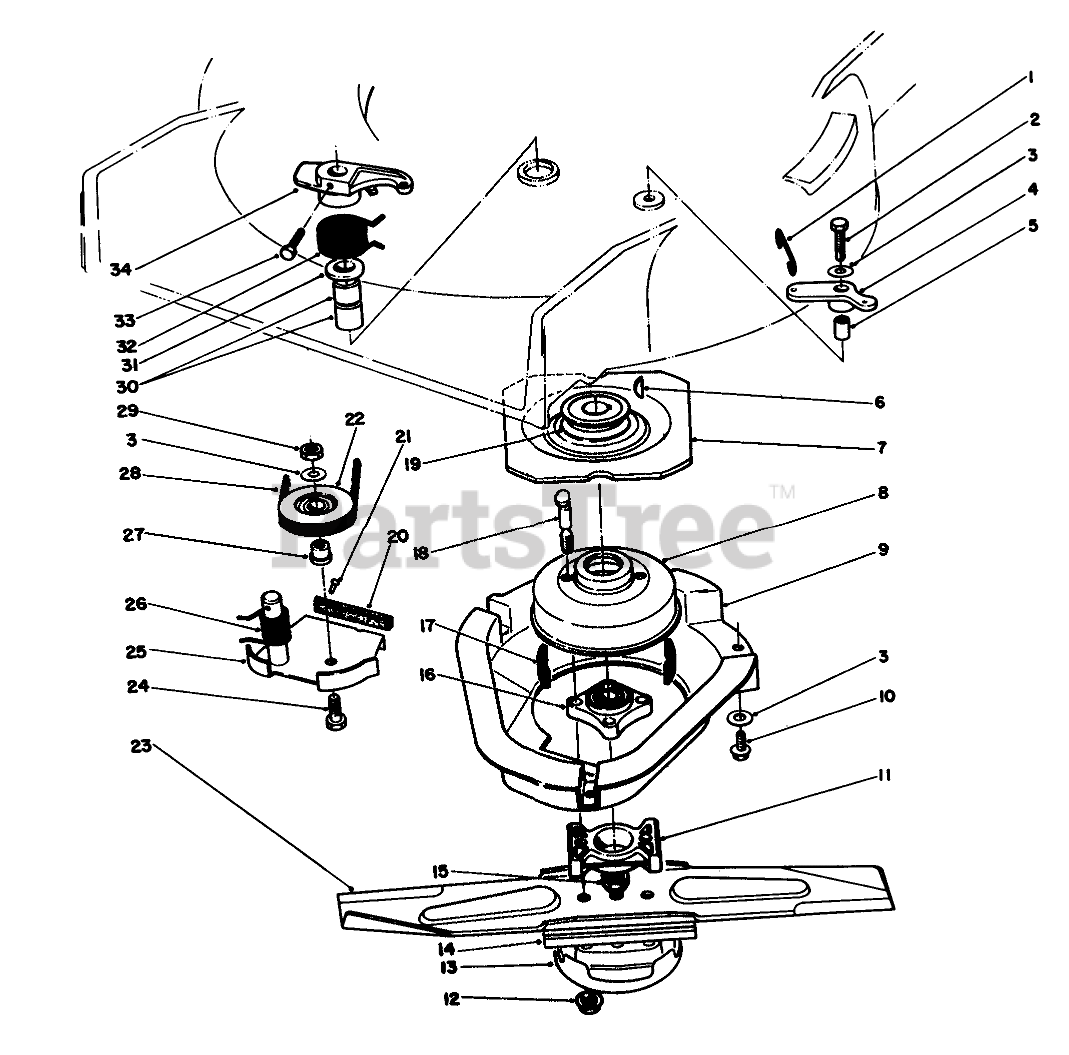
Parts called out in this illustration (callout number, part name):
1	LINK-CONTROL
2	SCREW-HH
3	WASHER-PLAIN
4	BELLCRANK
5	SLEEVE-BELLCRANK
6	KEY-WOODRUFF
7	Flywheel
8	Drum-Brake
9	SHIELD BBC
10	SCREW-HWHTF
11	SPACER-BLADE
12	NUT-LOCK
13	CUP-SCALP, ANTI
14	Stiffener
15	NUT-LOCK, NI
16	HUB ASM
17	DAMPENER-VIBRATION
18	BOLT-BLADE
19	PULLEY
20	Pad-Brake
21	.185 DIA X .375 RT +
22	PULLEY-IDLER
23	Blade
24	SCREW-HH
25	Brake Plate (Incl. Ref. #20 & 21)
26	SPRING-TORSION
27	HUB-PULLEY, IDLER
28	V-BELT
29	NUT-LOCK, NI
30	BEARING
31	WASHER
32	SPRING-TORSION
33	SCREW-HH
34	LEVER
